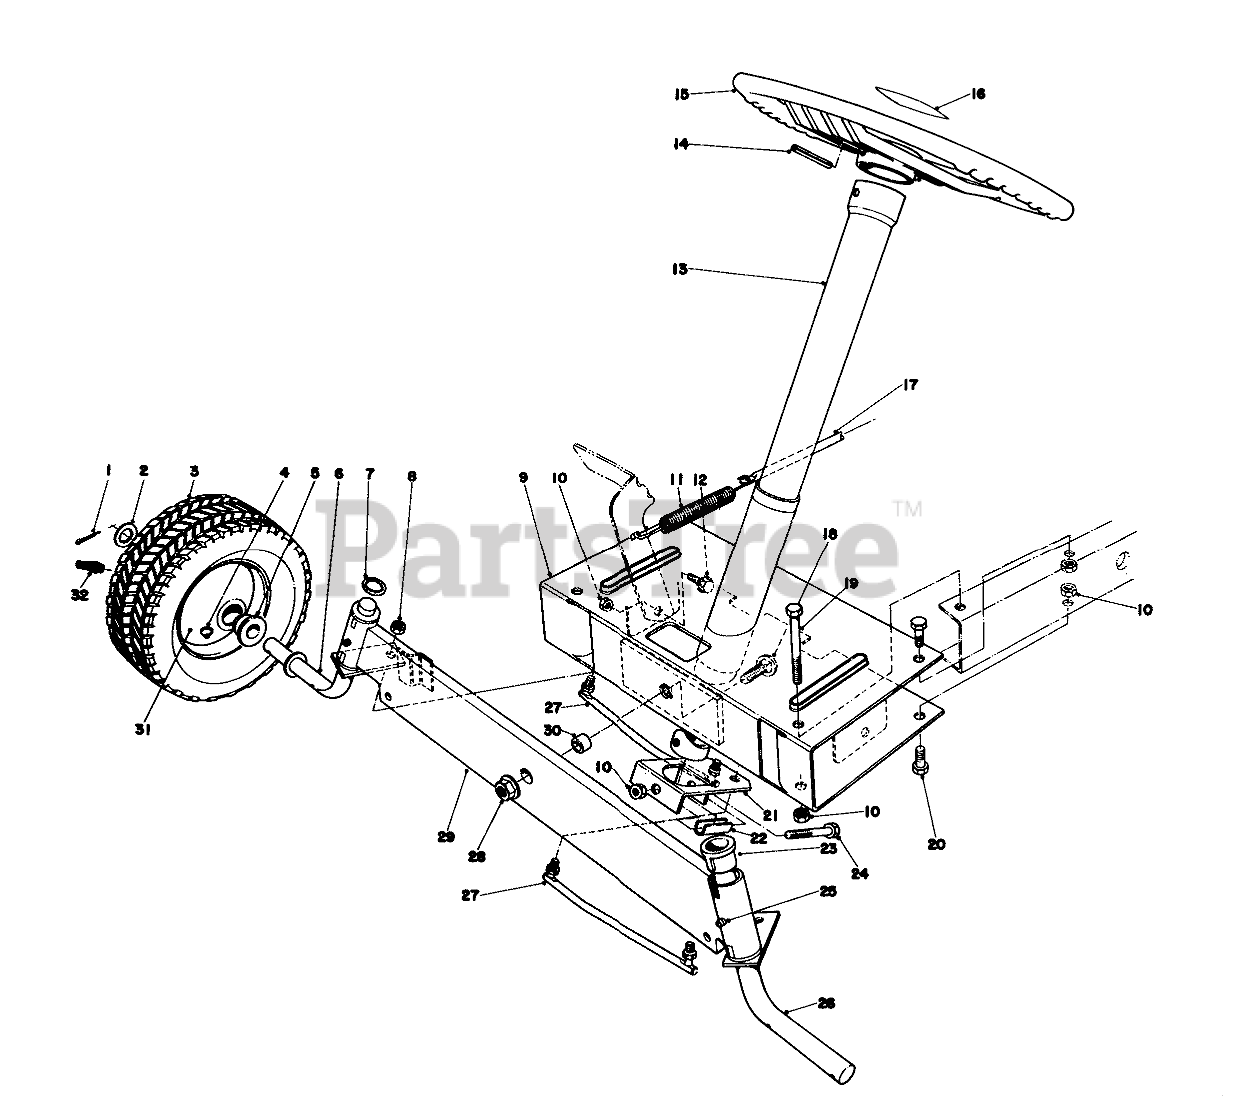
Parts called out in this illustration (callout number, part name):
1	PIN-COTTER
2	WASHER-FLAT
3	Tire Turf King
4	FITTING-GREASE
5	BUSHING
6	SPINDLE WA RH
7	Retaining Ring
9	Front Frame
10	NUT-LOCK, CONE
11	Brake Spring
12	SCREW-SHOULDER
13	Steering Tube
14	PIN-ROLL
15	Steering Wheel
16	Decal
17	Brake Rod
18	SCREW-CARR
19	SCREW-HH
20	SCREW-HH
21	Lever Steering
22	Spacer-Steering Tube
23	BUSHING
24	SCREW-HH
25	Fitting-Grease
26	Spindle L.H.
27	TIE ROD ASM
28	NUT-HF
29	Front Axle
30	FRONT AXLE SPACER
32	STEM-VALVE
